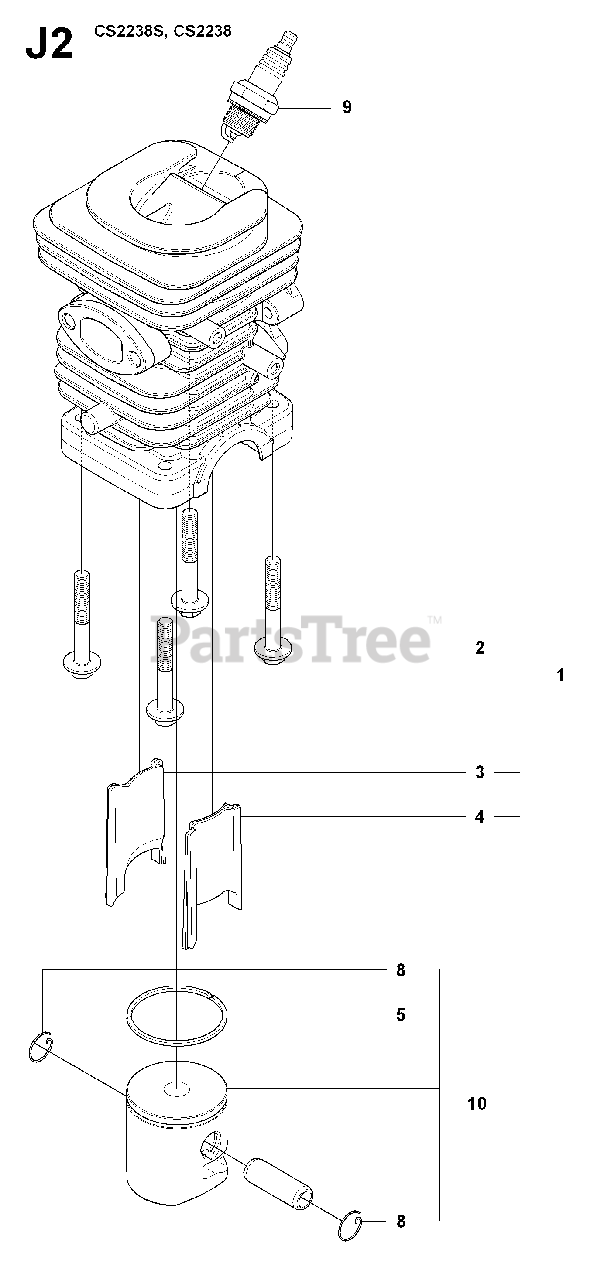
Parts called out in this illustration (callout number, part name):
1	%KIT, CYLINDER & PISTON
2	BOLT
3	INSERT TRANSFER LEFT
4	INSERT TRANSFER RIGHT
5	PISTON RING
8	C-CLIP,PSTN PIN 36/41
9	SPARK PLUG RCJ7Y
10	PISTON KIT
